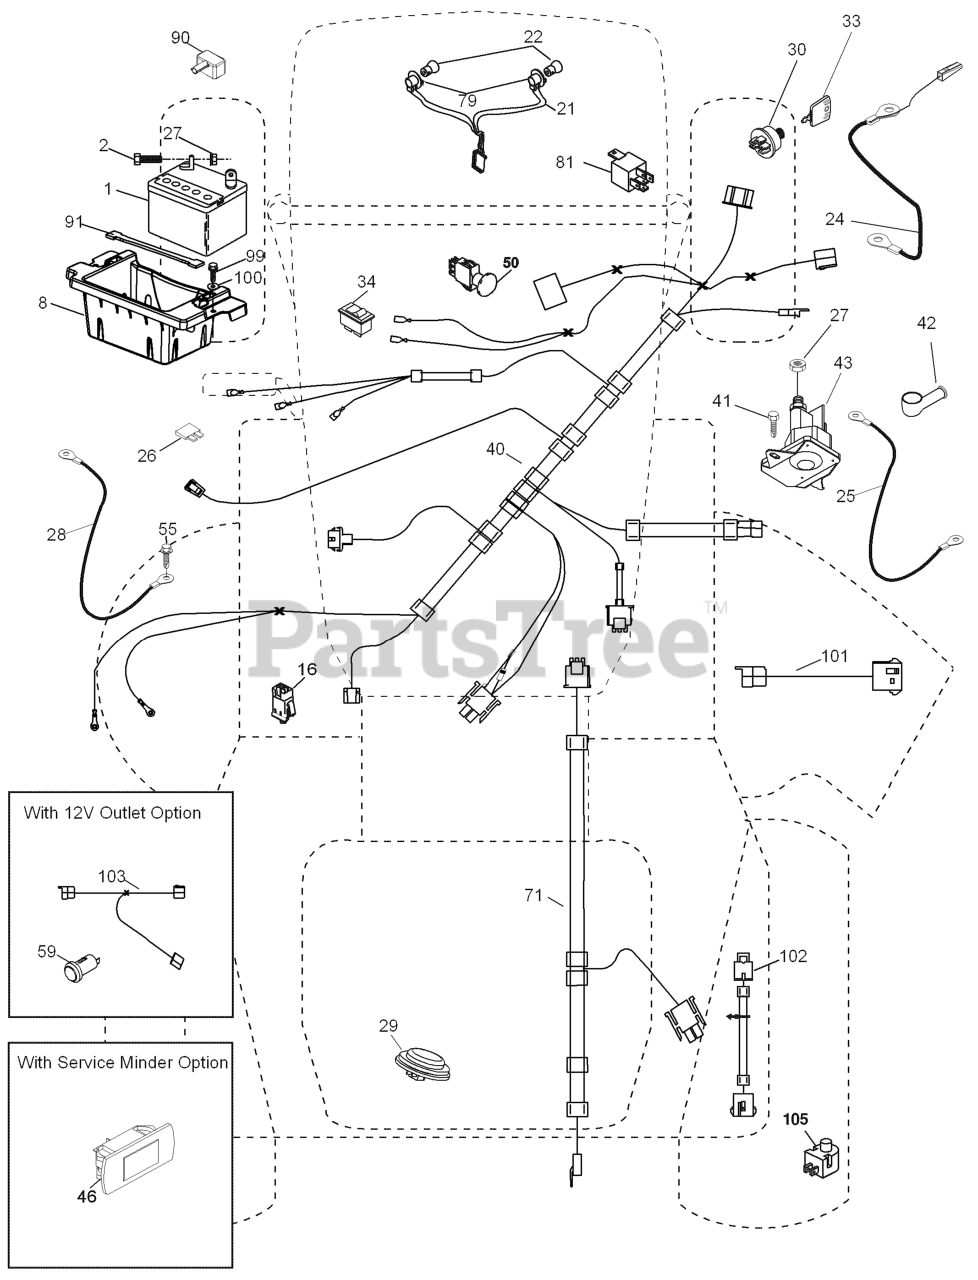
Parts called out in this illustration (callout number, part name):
1	Battery
2	BOLT.HEX.1/4.X.3/4.DICHROMATE
8	BOX.BATTERY.MOUNT.FRONT.LT
16	SWITCH INTERLOOK PUSH-IN
21	HARNESS ASSY LIGHT
24	CABLE.BATT.POS.WIRE.TG.DA SOL
25	CABLE.STARTER.6G.BL/RED.17.5
26	FUSE 20AMP
27	NUT
28	CABLE GROUND 6 GA 21" 90T BLK
29	SWITCH.SEAT.DELTA.OPC.
30	SWITCH.IGN.DELTA.W.LGH.ROS
33	KEY.CHAIN.BLISTER.PACK.GEN.INT
40	HARNESS.IGN.ELE.RELAY.TEX.46"
41	SCREW
42	TERMINAL COVER
43	SOLENOID.W/BRASS.PLUNGER
46	RP.GUAGE.SRVCMNDR.HRMTR.
50	RP.PTO.SWITCH.8 TERMINAL.BLACK
55	SCREW 5/16"
59	OUTLET.12-VOLT
71	HARNESS-CHASSIS SUB
79	BULB HOLDER ASM.
81	RELAY HARNESS.SEALED
90	COVER.TERMINAL.BATTERY
91	STRAP.BATTERY.MOUNT.FRONT(2 2)
99	SCREW HEXWSHR 1/4-20X3/4
100	WASHER
101	PIGTAIL.MATNLK.NEW.HAR
102	HARNESS PIGTAIL PCH TEX ROS
103	HARNESS PIGTAIL 12V OUTLET
105	REVERSE SWITCH
